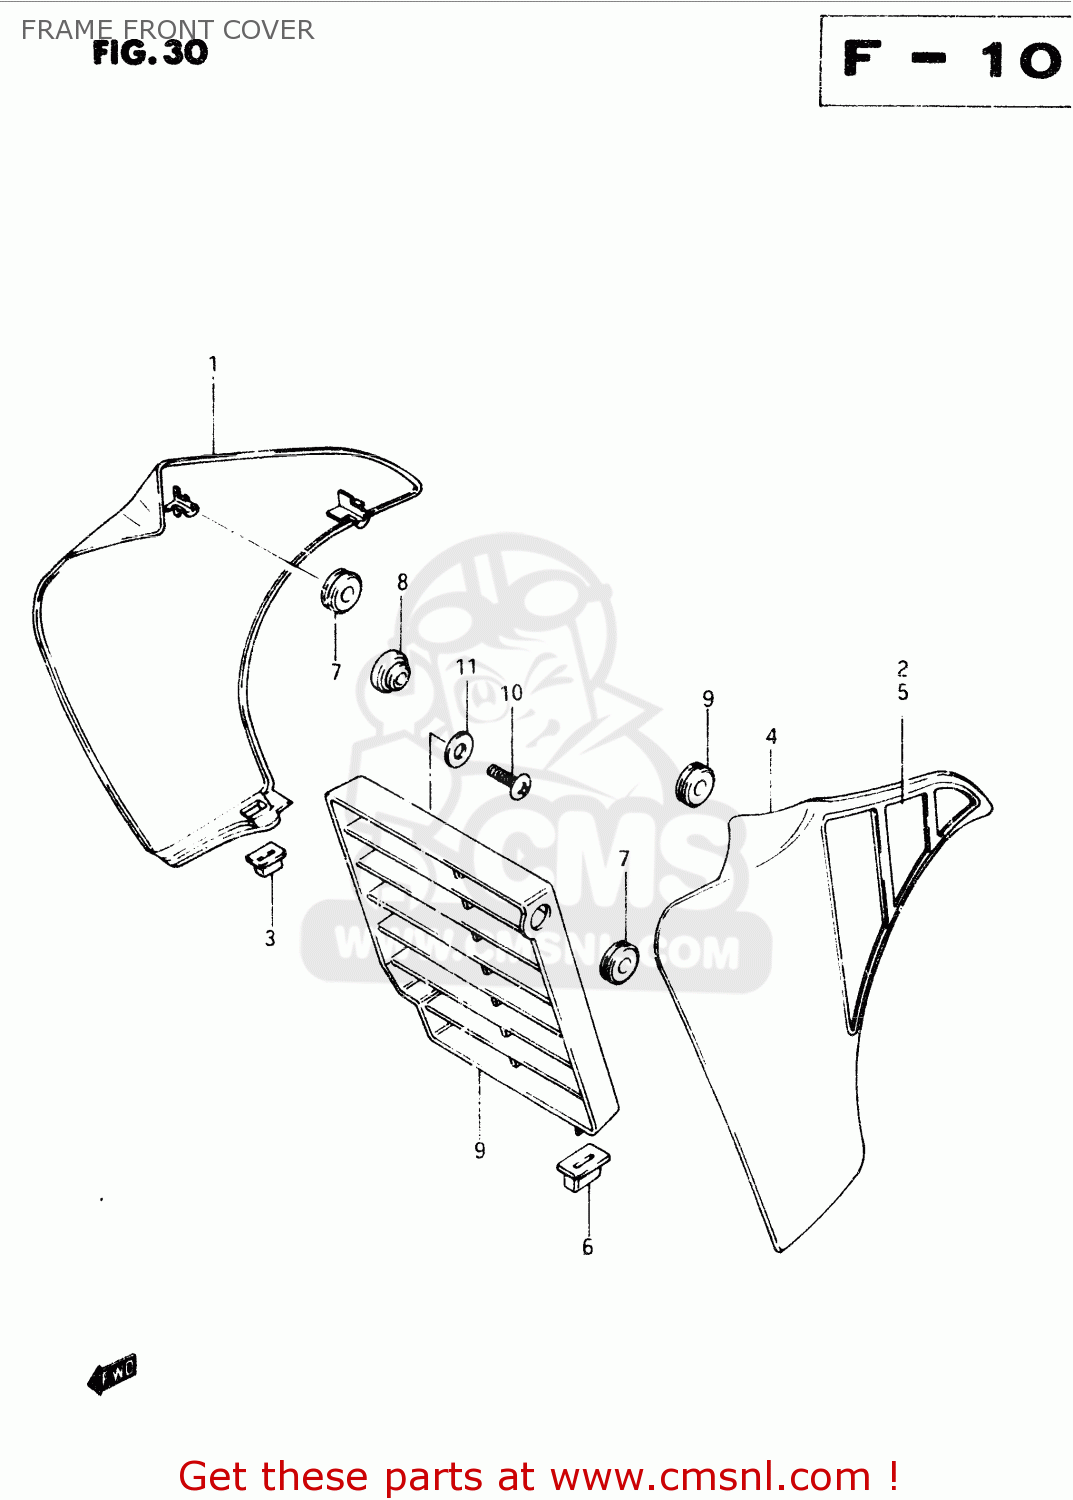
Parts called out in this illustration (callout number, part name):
1	COVER,FRAME FR
2	TAPE SET, FRONT RH (BLUE)
3	CUSHION RADI C
4	COVER,FRAME FR,L
5	TAPE SET, FRONT LH (BLUE)
6	CUSHION,FRAME FR COVER,L
7	CUSHION
8	CUSHION
9	LOUVER,FRAME FR
10	SCREW
11	WASHER
